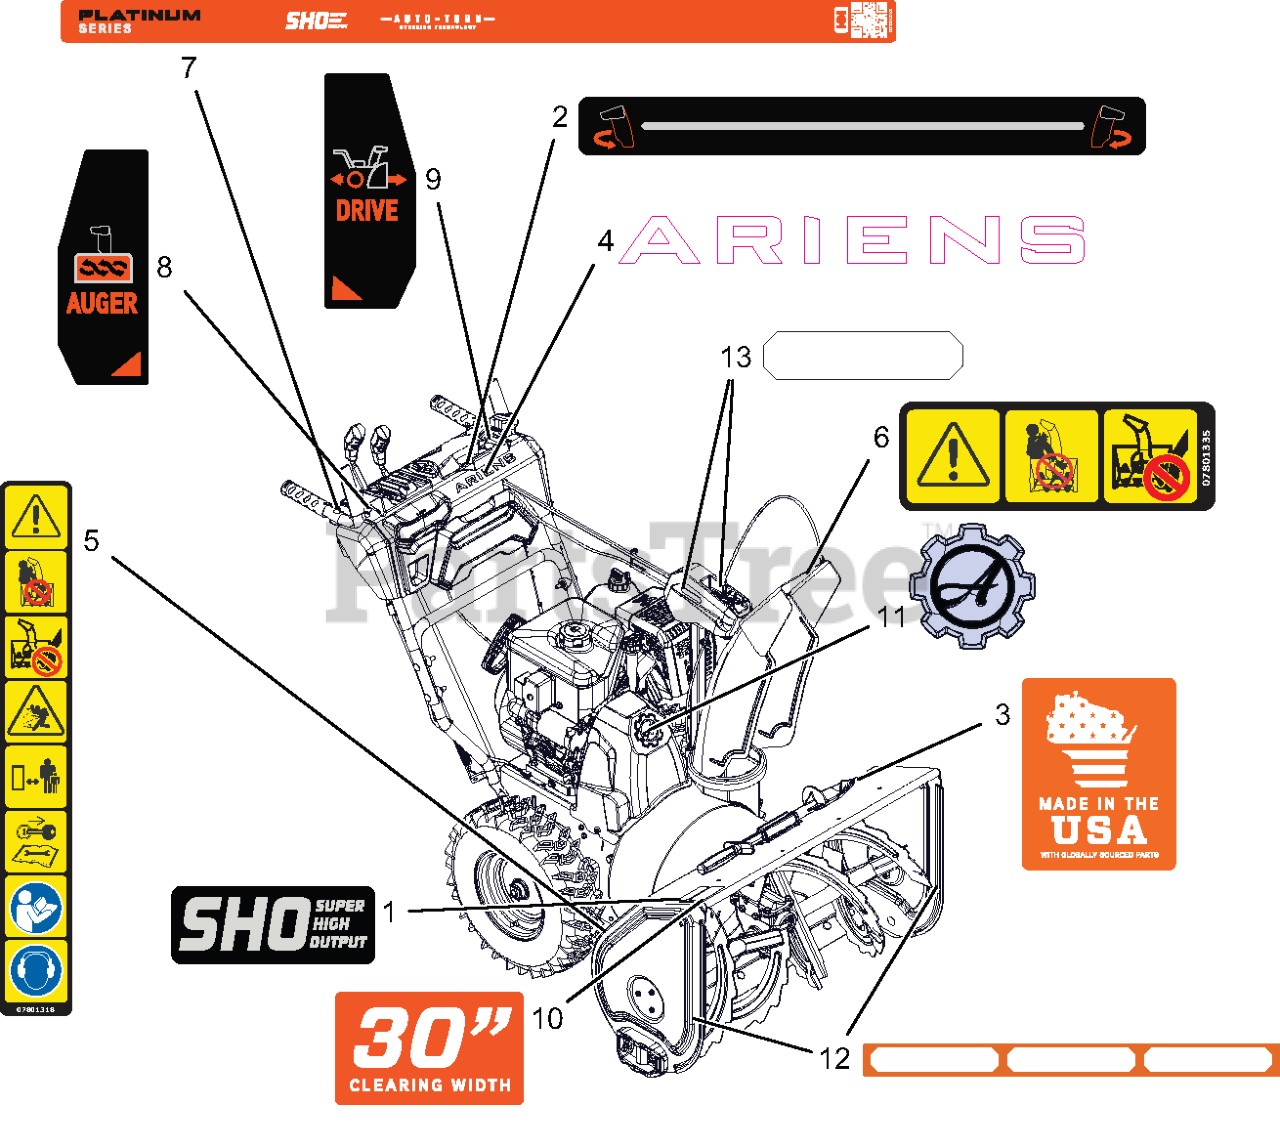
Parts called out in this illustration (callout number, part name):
1	DECAL, SHO
2	DECAL- CHUTE ROTATION
3	DECAL- MADE IN USA
4	DECAL- ARIENS - 7.46"
5	DECAL- SAFETY - DANGER
6	DECAL- DANGER
7	DECAL- DASH - PLT
8	DECAL- CONTROL - AUGER
9	DECAL- CONTROL - DRIVE WHEEL
10	DECAL- CLEARING - 30
11	DECAL- ARIENS GEAR BADGE
12	DECAL,REFLECTIVE,HOUSING
13	DECAL,REFLECTIVE,GEAR COVER
